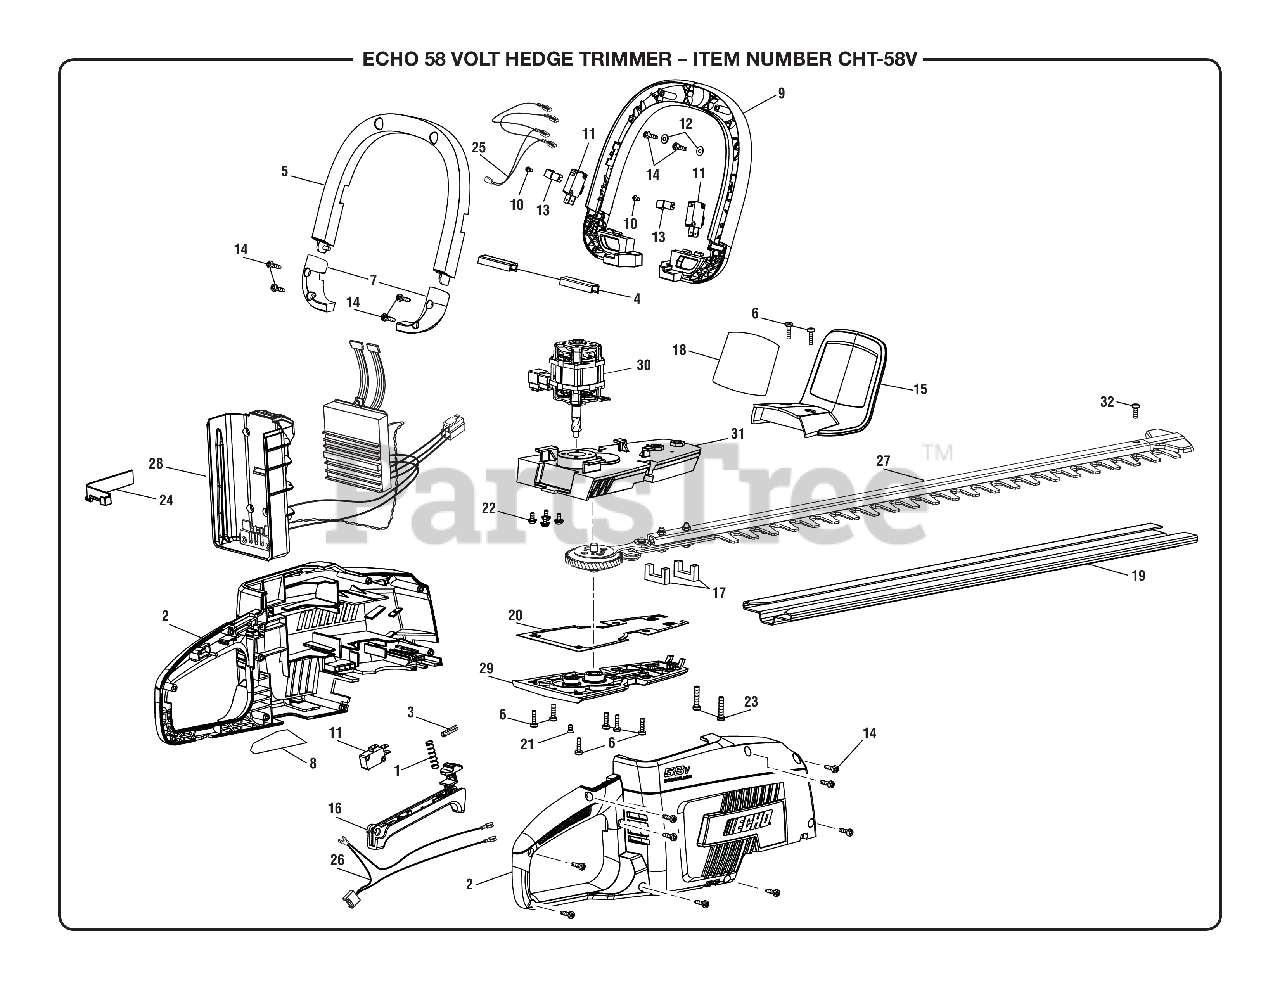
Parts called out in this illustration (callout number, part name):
1	Handle Cover Spring
2	Housing Assembly
3	Lock-out Button Spring
4	Wire Cover Assembly
5	Front Handle Trigger
6	Screw (M4 x 15 mm, T25 Torx Round Hd.)
7	Front Handle Cover Assembly
8	Data Label
9	Front Handle Support
10	Screw (M3 x 6 mm, Pan Hd.)
11	Switch (On/Off)
12	Washer (4.2ID x 10OD x 1t)
13	Switch Board
14	Screw (M4 x 18 mm, T25 Torx Hd.)
15	Guard (Inc. Key No.18)
16	Trigger Assembly
18	Warning Icon Label
19	SCABBARD
21	Screw (M4 x 6 mm, Flat Hd.)
22	Screw (M4 x 9.5 mm)
23	Screw w/Washer (M5 x 27 mm, T25 Torx Round Hd.)
24	Wire Cover
25	Front Handle Wire Assembly
26	Rear Handle Wire Assembly
27	Blade and Gear Assembly
28	Circuit Board and Battery Carriage Assembly
29	Gear Box Cover Assembly
30	Motor and Pinion Assembly
31	Gear Box Case Assembly
32	Screw (M5 x 20 mm, T20 Torx Hd.)
